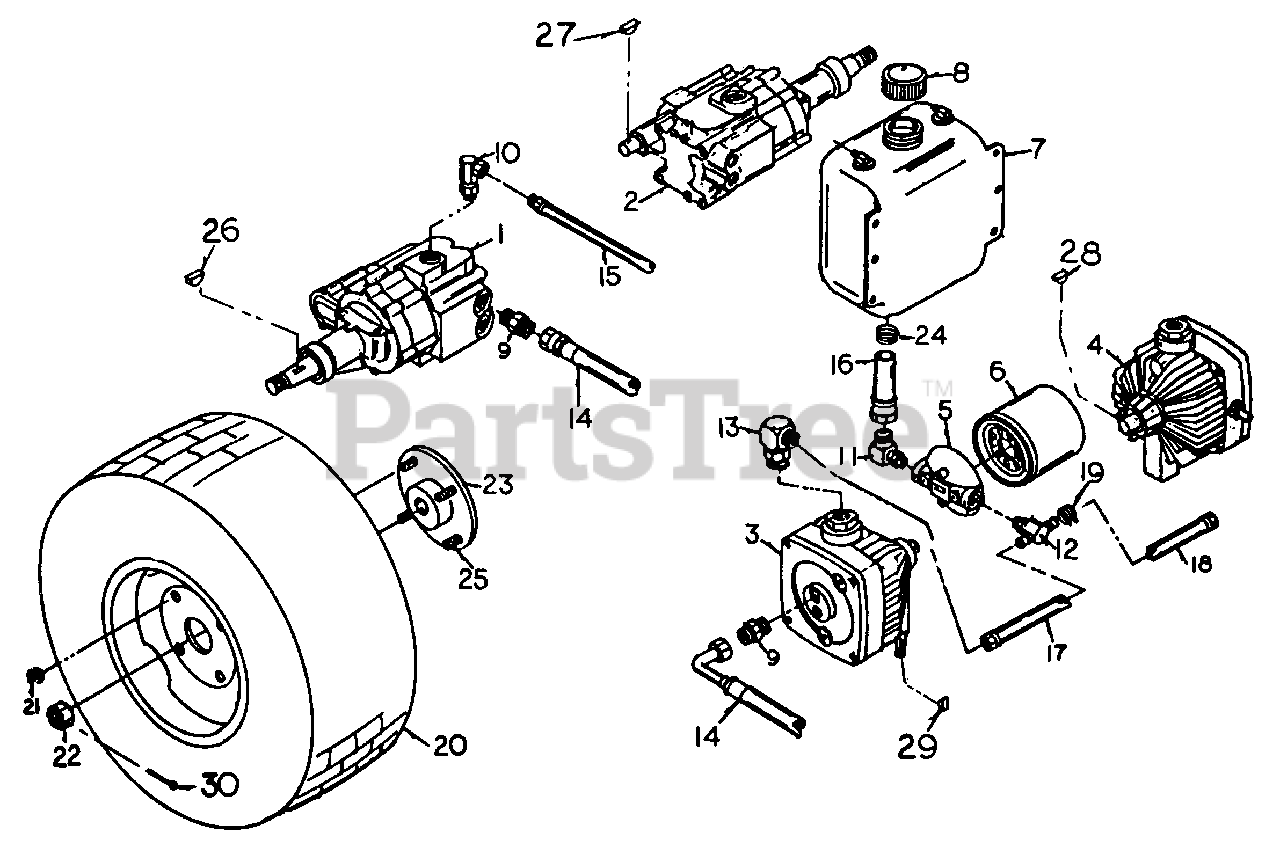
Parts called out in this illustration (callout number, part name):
1	Wheel Motor, LH
2	Wheel Motor, RH
3	Pump, LH
4	Pump, RH
5	Housing, Oil Filter
6	Element, Oil Filter
7	3 Qt. Oil Tank
9	Male Tube, Male O-ring Adp.
10	Male O-ring, 90ø Female Pipe Swivel Adp.
11	Male O-ring, 90ø Male Tube Adp.
12	Male O-ring, 1/2" Hose Barb Tee
13	Male O-ring, 90ø Male Tube Adp.
14	Hose, 1/2" ID x 28" Long
15	Hose, 1/4" ID x 24" Long, Easy Couple
16	Hose, 5/8" ID x 7" Long, Easy Couple
17	Hose, 1/2" ID x 15" Long, Easy Couple
18	Hose, 1/2" ID x 21" Long, Easy Couple
19	Hose Clamp, 1/2"
20	Wheel Ass'y., 18 x 9.50-8
21	Lug Nut, 1/2-20
22	Nut, Wheel Motor
23	4-Bolt Wheel Hub
24	Hose Clamp, 5/8"
25	Lug Bolt, 1/2-20 x 1 1/4"
26	Woodruff Key, 3/16" x 1"
27	Woodruff Key, 3/16" x 3/4"
28	Woodruff Key, 1/8" x 1/2"
29	Woodruff Key, 1/8" x 3/8"
30	Cotter Pin, 1/8" x 1 3/4"
